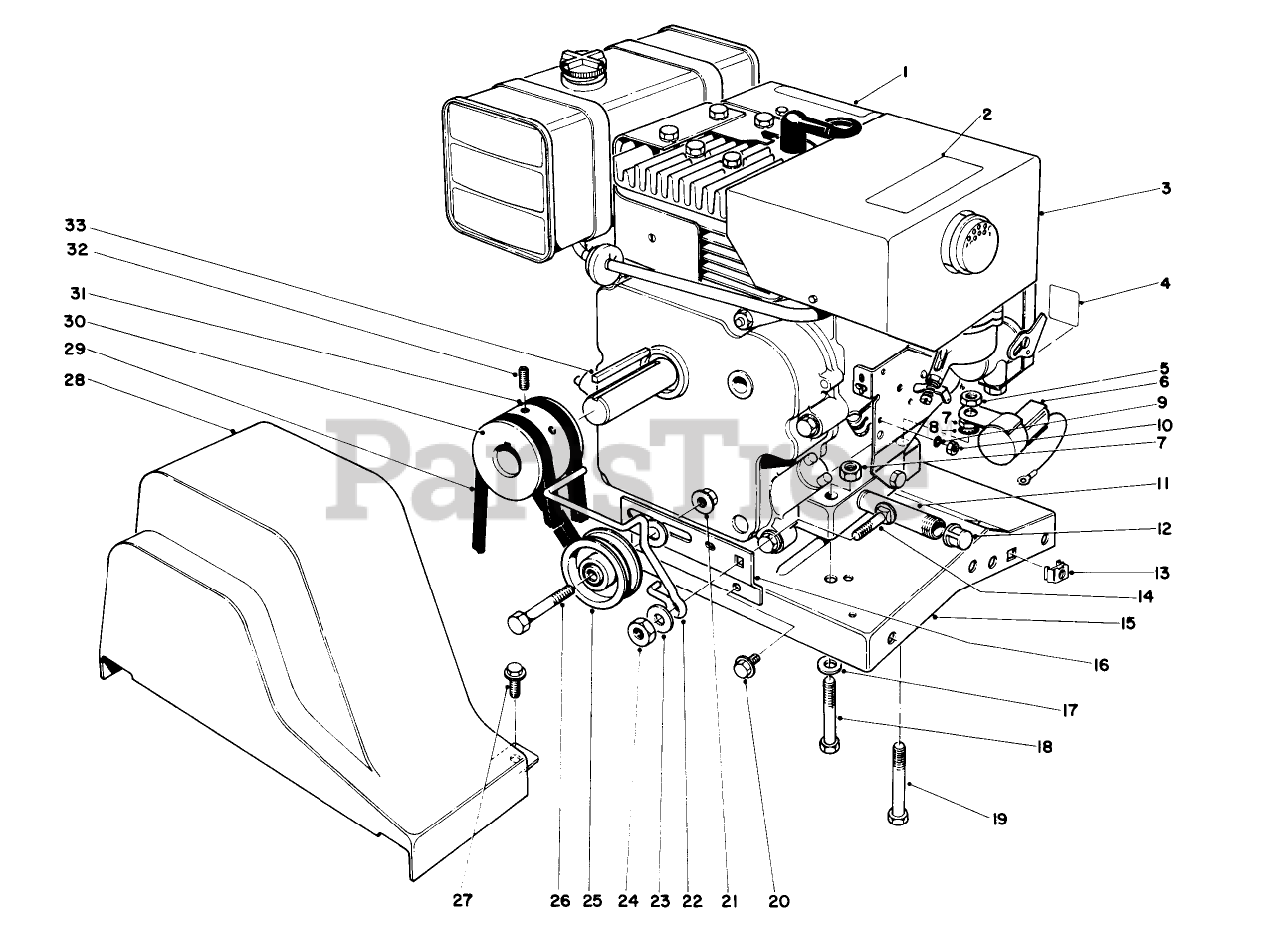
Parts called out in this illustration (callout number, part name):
1	Decal-Hazard
2	Decal Hot Surface Warning
3	Engine
4	CHOKE DECAL
5	NUT-HEX, SIDE DEFORM
6	INTERLOCK MODULE
7	NUT-LOCK, NI
8	WASHER-LOCK, INTERNAL
9	WASHER-LOCK/INT
10	NUT-LOCK
11	NIPPLE-PIPE
12	CAP-PIPE
13	RETAINER NUT
14	SCREW-CARR
15	Base-Engine
16	BELT IDLER BRKT
17	WASHER-PLAIN
18	SCREW-HH
19	SCREW-HH
20	SCREW-HHFTF
21	NUT-HHF, WHIZ
22	BELT GUIDE
23	WASHER-FLAT
24	NUT-HEX
25	PULLEY B
26	SCREW-HH
27	SCREW-HWH
28	BELT GUARD
29	V-BELT
30	ENGINE PULLEY
31	V-BELT
32	Screw-Set
